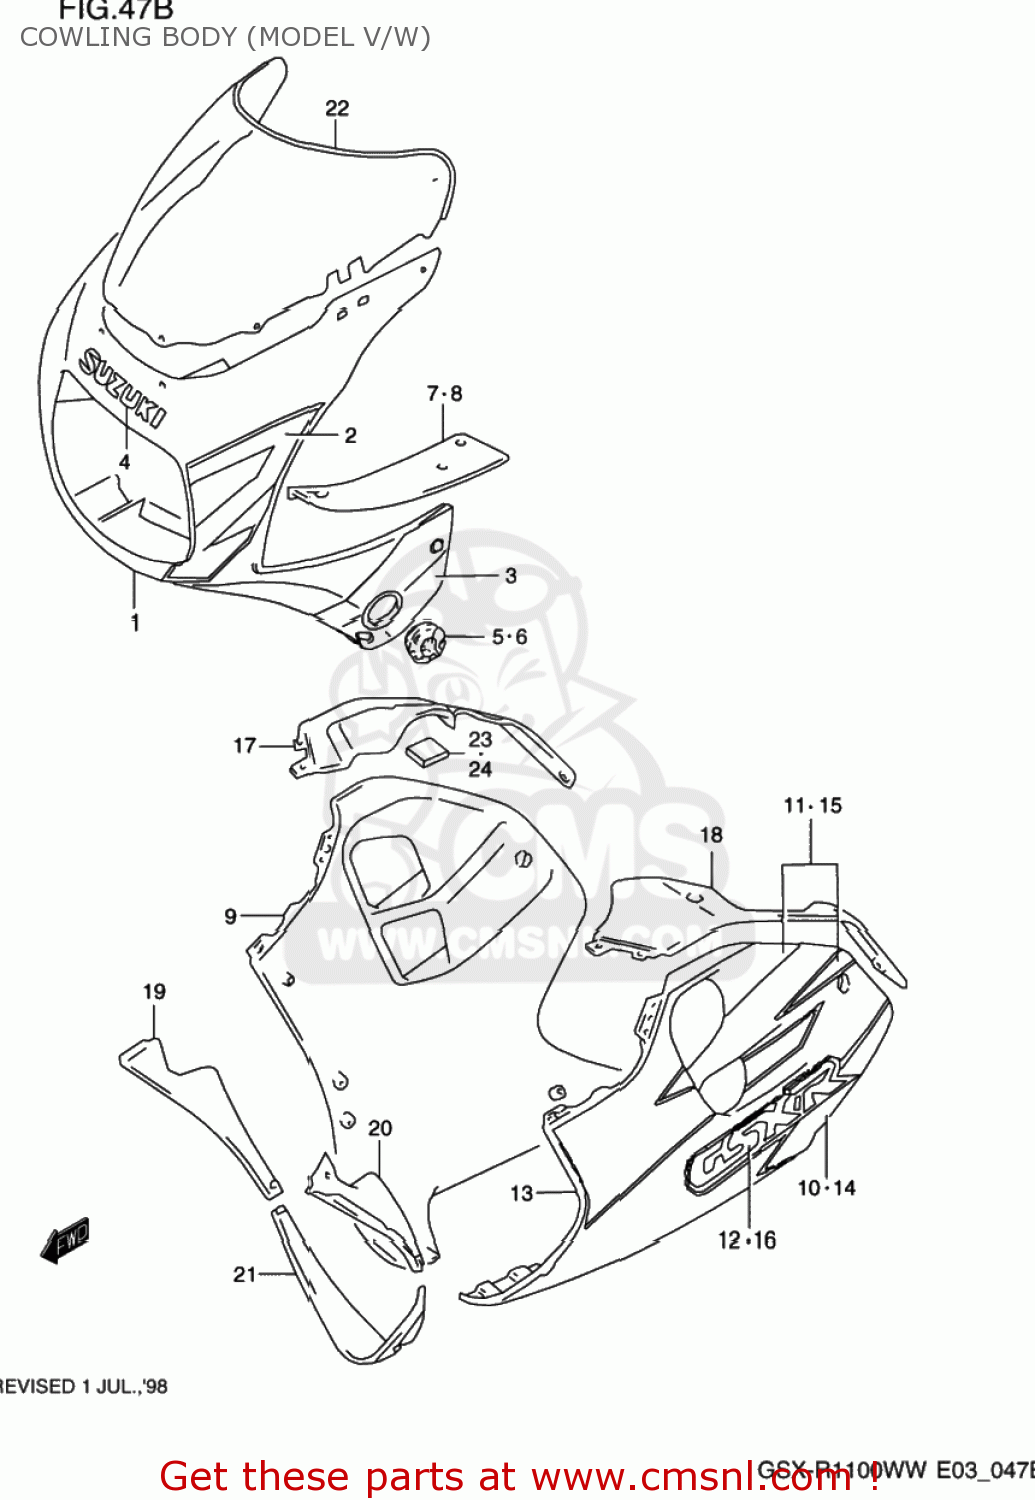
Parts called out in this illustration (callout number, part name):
1	COWLING ASSY,BODY
2	TAPE SET,BODY COWLING,FRONT
3	TAPE SET,BODY COWL SIDE
4	EMBLEM,BODY COWL
5	PLATE,TURN SIGNAL,RIGHT
6	PLATE,TURNSIGNAL LAMP,L
7	PANEL,COWLING UPR,R
8	PANEL,COWLING UPR,L
9	COWLING ASSY,UNDER,R
10	TAPE,COWL UNDER,R
11	TAPE SET,COWL UNDER,R
12	EMBLEM,COWLING UNDER
13	COWLING ASSY,UNDER,L
14	TAPE,COWL UNDER,L
15	TAPE SET,COWL UNDER,L
16	EMBLEM,COWLING UNDER
17	PANEL,LWR,R
18	PANEL,LWR,L
19	COWLING,UNDER INNER,R
20	COWLING,UNDER INNER,L
21	COWLING,UNDER CTR
22	SCREEN SET,WINDOW
23	CUSHION,UNDER COWLING
24	CUSHION,CHAIN CASE
